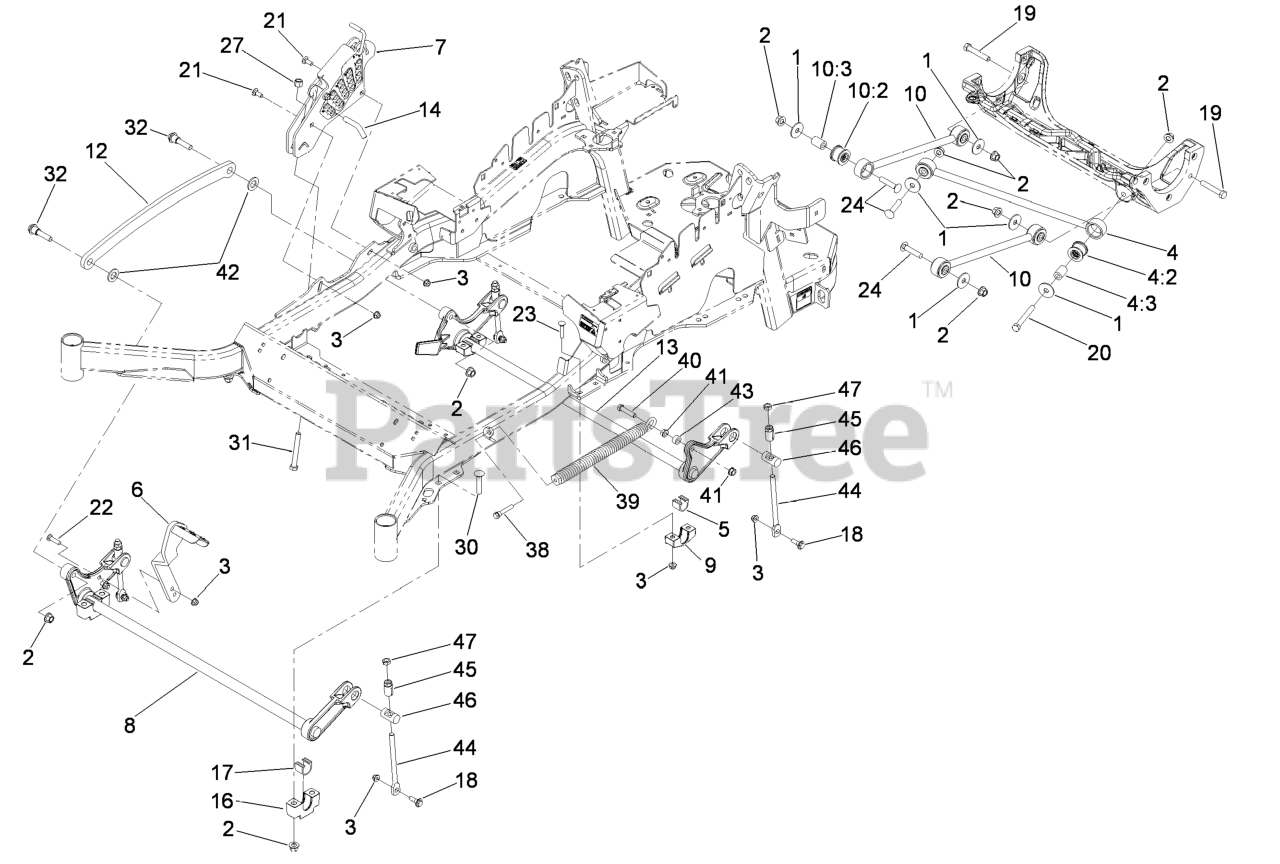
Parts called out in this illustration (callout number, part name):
1	WASHER-THRUST
2	Nut-Lock 1/2-13
3	NUT-HF, NI
4	PANHARD ROD ASM
4:2	BUSHING-SUSPENSION, RUBBER
5	BEARING-CROSS SHAFT, REAR
6	LEVER-FOOT
7	HOC ASM
10	DECK STRUT ASM
10:2	BUSHING-SUSPENSION, RUBBER
12	LINK-LIFT, DECK
13	LIFT-DECK, REAR
14	PIN-HOC
16	SUPPORT-CROSS SHAFT, BEARING
17	BEARING-CROSS SHAFT, FRON
18	SCREW-SHOULDER, HHF
19	SCREW-HH
20	SCREW-HH
21	BOLT-CARR
22	SCREW-CARR
23	SCREW-CARR
24	SCREW-CARR
27	NUT-LOCK, NI
30	Bolt-Carriage 1/2-13 X 2 1/2 Spl Neck
31	BOLT-TAP
32	SCREW-HHF, SHOULDER
38	BOLT-SHOULDER
39	SPRING-EXTENSION
40	SCREW-HH
42	WASHER-FLAT
44	LINK-ADJUSTER, DECK LIFT
45	ADJUSTER-LIFT, DECK
46	TRUNNION
47	NUT-JAM
